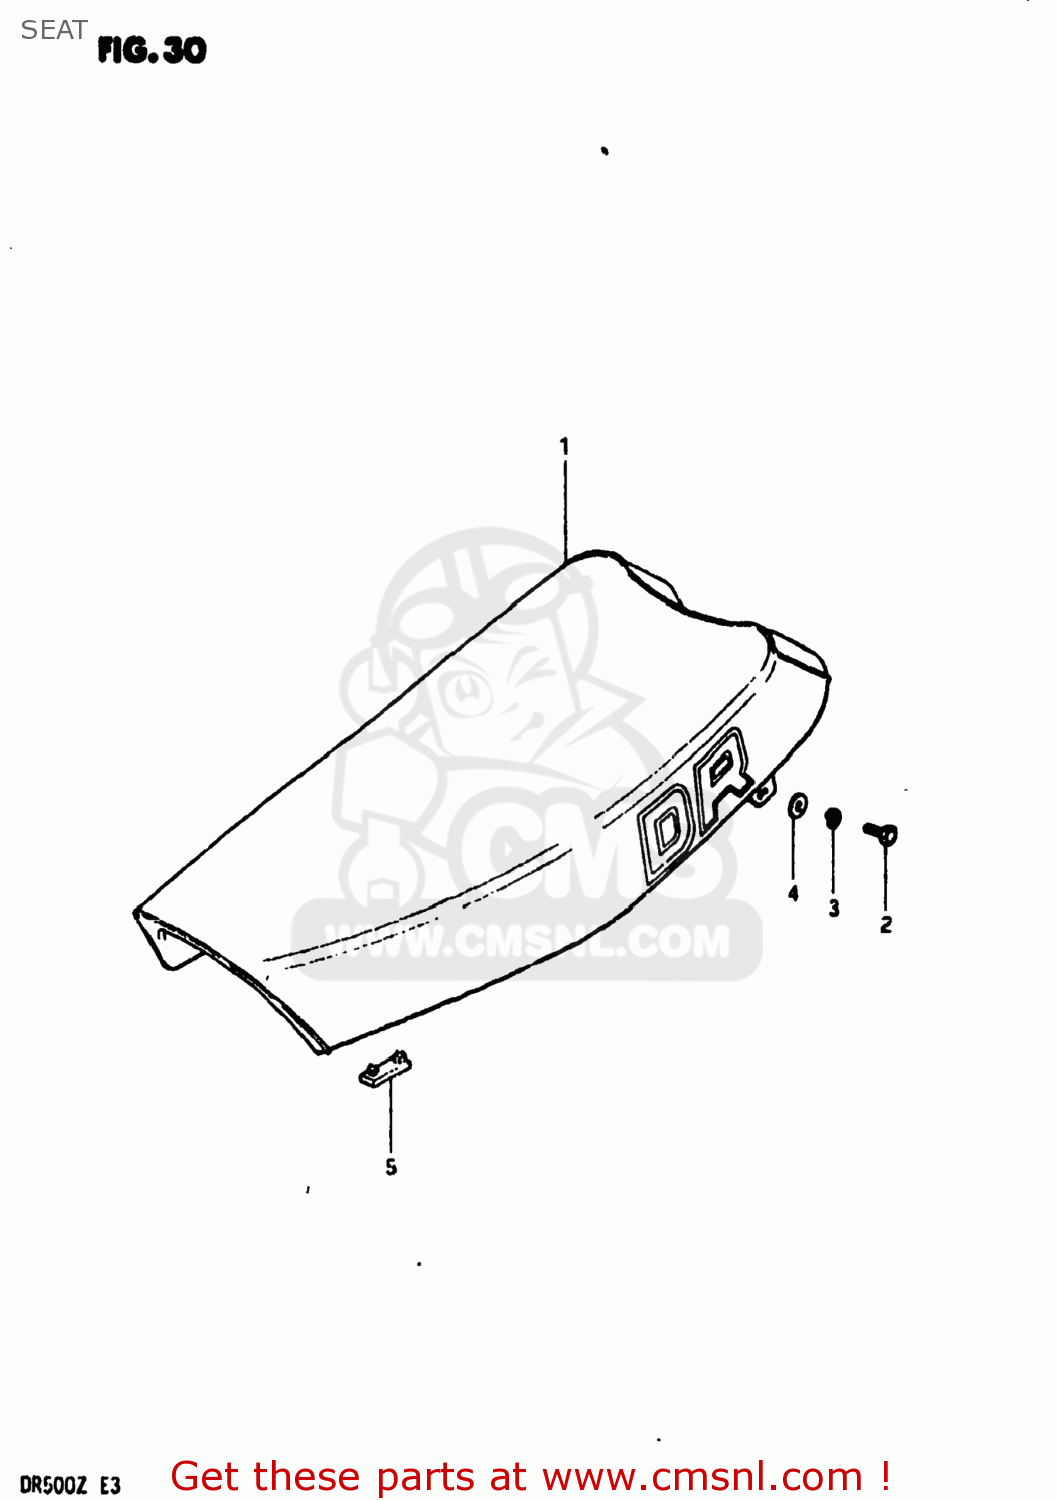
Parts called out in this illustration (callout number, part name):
1	SEAT ASSEMBLY
2	BOLT
3	WASHER,LOCK,8.
4	WASHER
5	CUSHION
